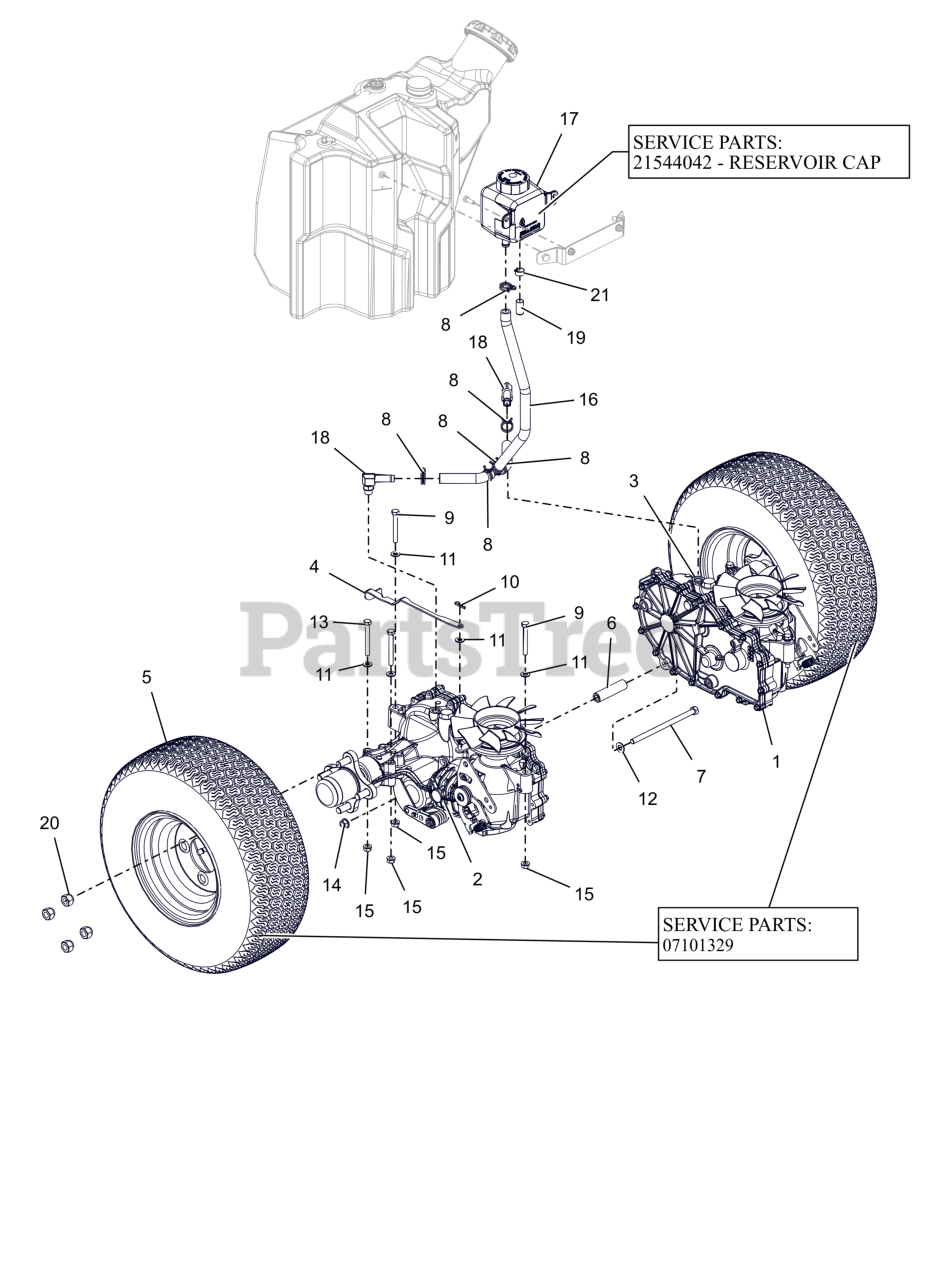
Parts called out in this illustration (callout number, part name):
1	TRANSAXLE, LH ZT3100
2	TRANSAXLE, RH ZT3100
3	BRKT, HYDRO DUMP - LEFT
4	BRKT, HYDRO DUMP - RIGHT
5	ASM, WHL/TIRE 18X6.50-8
5	TIRE, 18X6.50-R8
6	SHAFT, CROSS BRACE
7	BLT, HEX .38-16X6.50 G5 ZCC
8	3/4 WIRE HOSE CLMP ZC
9	BLT, HEX 0.3125-18X2.5 GR5 ZCC
10	PIN, HAIR #213 .08X1.19 ZCC
11	WSHR,FLT .344X.688X.065 ZCC
12	WSHR,FLT .406X.812X.065 ZCC
13	BLT, HEX .31-18X2.75 G5 ZCC
14	NUT-LK-CTR-FLG .375-16 GF ZCC
15	NUT,LK-CTR-FLG .31-18 GF ZCC
16	ASM, 32-36" OVERFLOW HOSE
17	TANK, HYDRO OVERFLOW 700 ML
17	CAP, HYDRO RESERVOIR REPLAC.
18	FITTING, HYD (90 DEG)
19	CAP, .50 BARBED FITTING
20	NUT, WHEEL .50-20 ZCC
21	CLAMP, .62 SPRING
